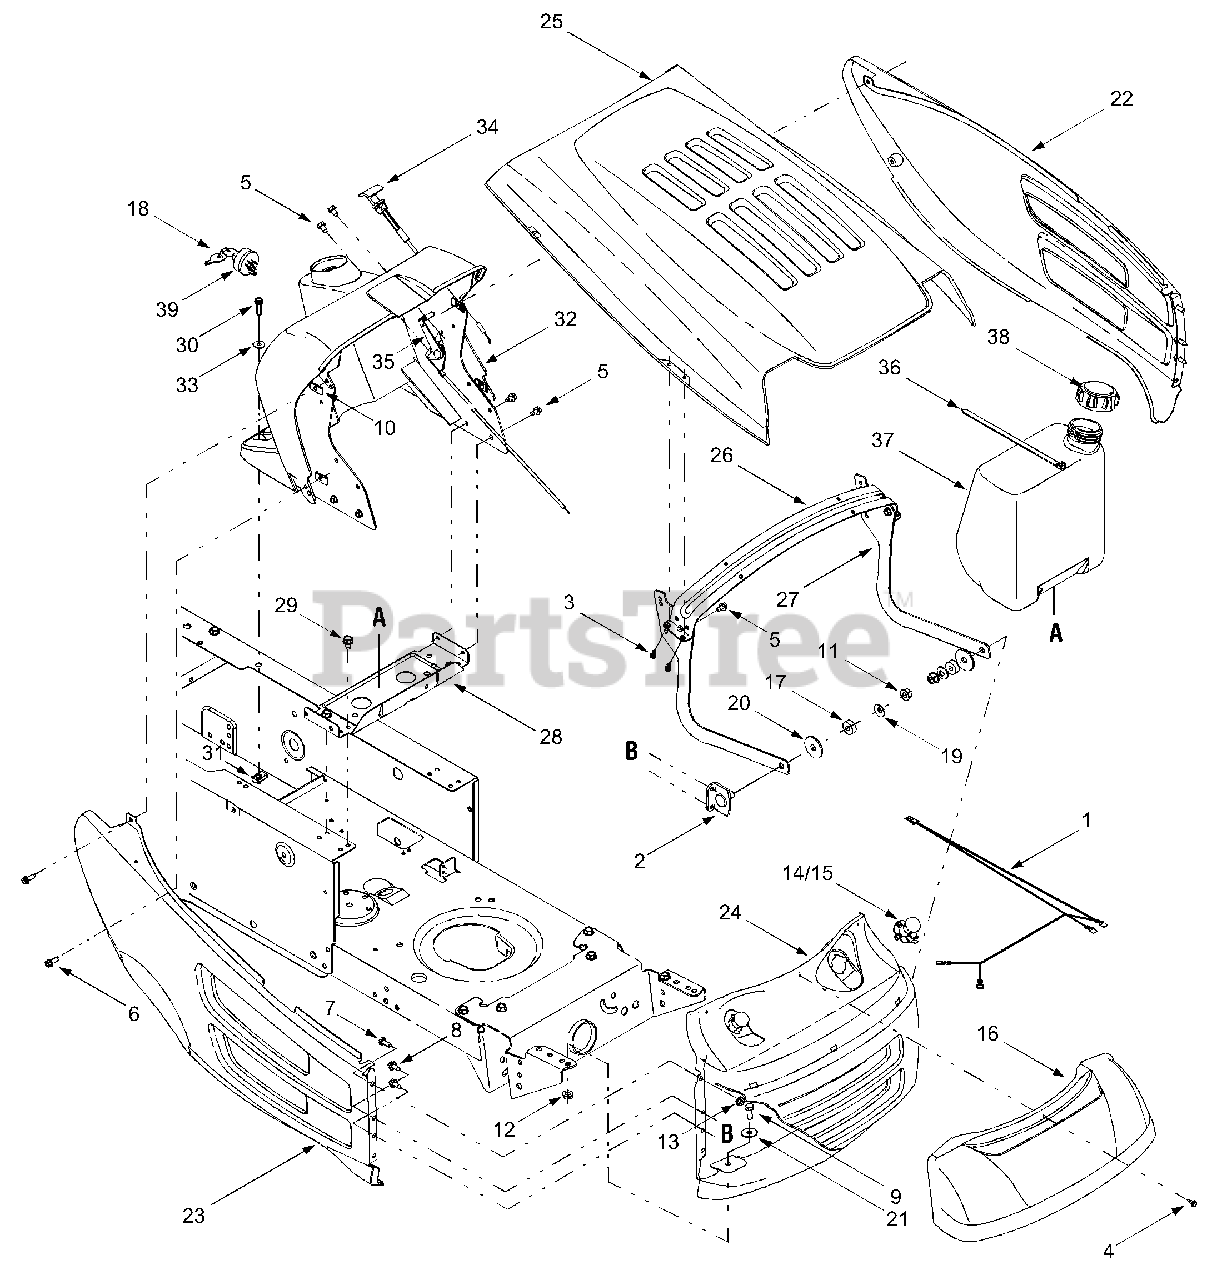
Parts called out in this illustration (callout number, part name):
1	Headlamp Harness Assembly
3	Screw, #10-16 x .50
4	Screw, #10-16 x .50
5	Self-tapping Screw, 1/4-20 x .5
6	Self-tapping Screw, 1/4-20 x .75
7	Hex Cap Screw:1/4-20 x .620
8	Hex Index Washer Screw, 1/4-14 x .0625
9	Hex Screw, 5/16-18 x .75
10	U-type Speed Nut, 1/4-20
11	Flange Lock Nut, 3/8-16
12	Lock Nut, 5/16-18
13	Flange Lock Nut, 1/4-20
14	Headlamp, 12V
15	Headlamp Socket
16	Headlight Lens (8-style)
17	Rubber Washer, .87 x .33
18	Keys (pair)
19	Flat Washer, .406 x .875 x .059
20	Flat Washer, .406 x 1.5 x 11 gauge
21	Flat Washer, .344 x 1.0 x .063
30	Self-tapping Screw, 1/4-20 x 1.0
31	U-type Speed Nut, 1/4-20
32	Dash Panel
33	Flat Washer, .260 x .720 x .060
34	Choke Control, 38"
35	Throttle / Choke Control, 18.5"
36	Cable Tie, 30.66
37	Fuel Tank, 1.5 gal.
38	Fuel Tank Cap
39	Ignition Switch, 6-pin
